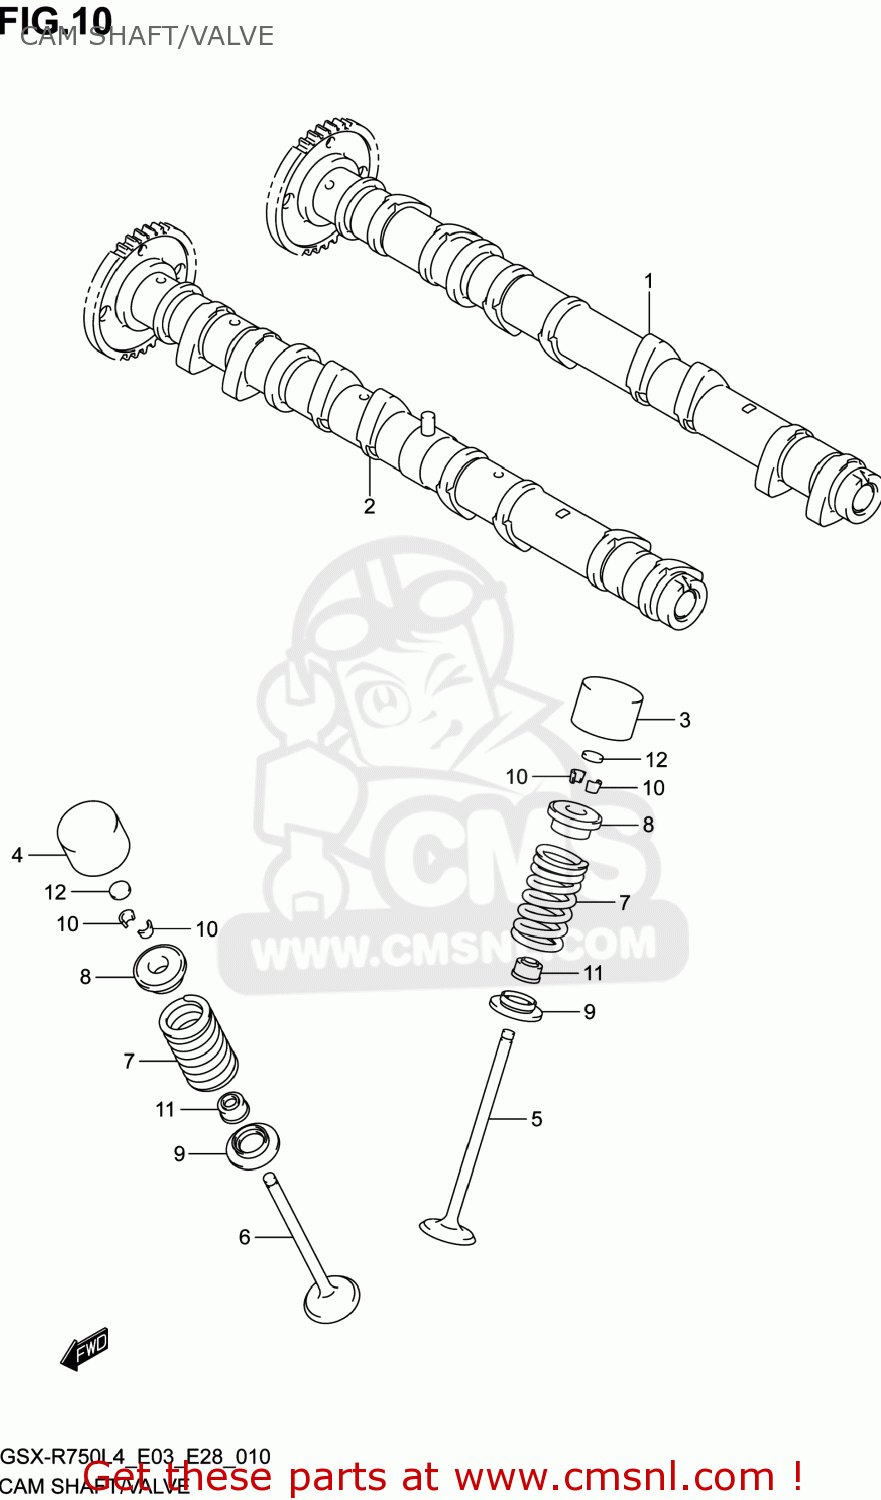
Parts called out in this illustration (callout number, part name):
1	CAMSHAFT,INTAKE
2	CAMSHAFT,EXHAUST
3	TAPPET
4	TAPPET,EXHAUST
5	VALVE,INTAKE
6	VALVE,EXHAUST
7	SPRING,VALVE
8	RETAINER,VALVE SPRING
9	SEAT,VALVE SPRING
10	COTTER VALVE
11	SEAL,OIL(4.5X10X8)
12	SHIM,TAPPET
13	SHIM SET,TAPPET
14	CASE,TAPPET SHIM
